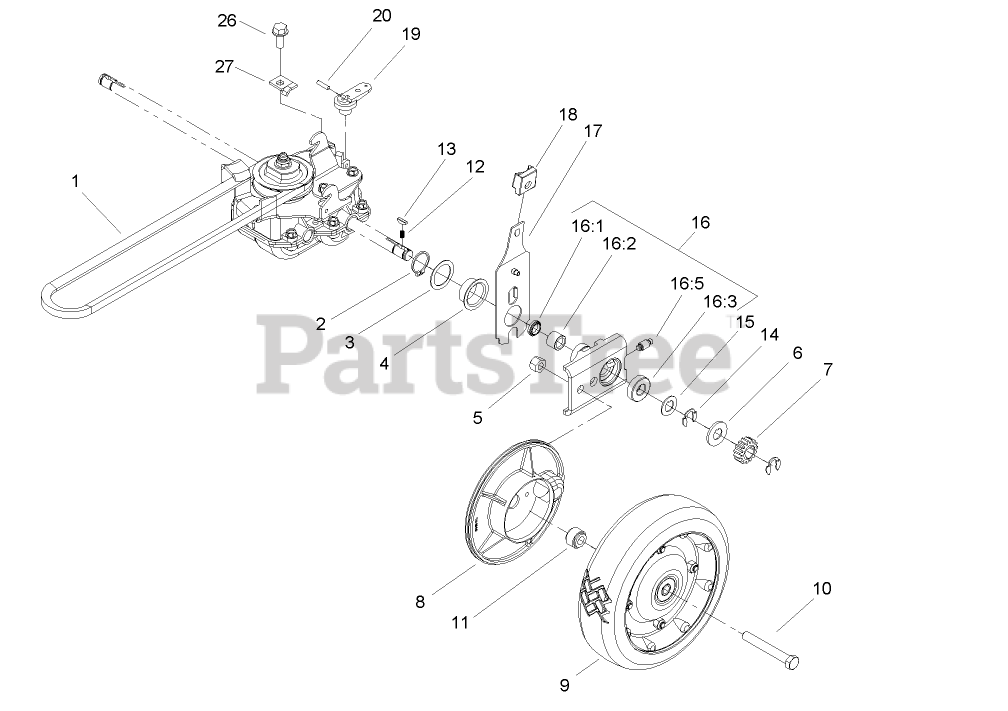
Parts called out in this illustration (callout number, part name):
1	V-BELT
2	RING-RETAINING
3	WASHER
4	CAP-END
5	NUT-LOCK, CONE
6	WASHER-THRUST, OUTER
7	GEAR-PINION
8	COVER-WHEEL
10	SCREW-HH
11	SPACER-COVER, WHEEL
12	SPRING-COMPRESSION
14	RING-RETAINING
15	WASHER-THRUST, OUTER
16	PIVOT ARM ASM
16:1	SEAL-OIL
16:3	BEARING-WHEEL
17	REAR SPRING ARM ASM
18	KNOB-ARM
19	LEVER-SHIFT
20	PIN-SPRING
26	SCREW-HWHTF
27	CLAMP-CABLE
